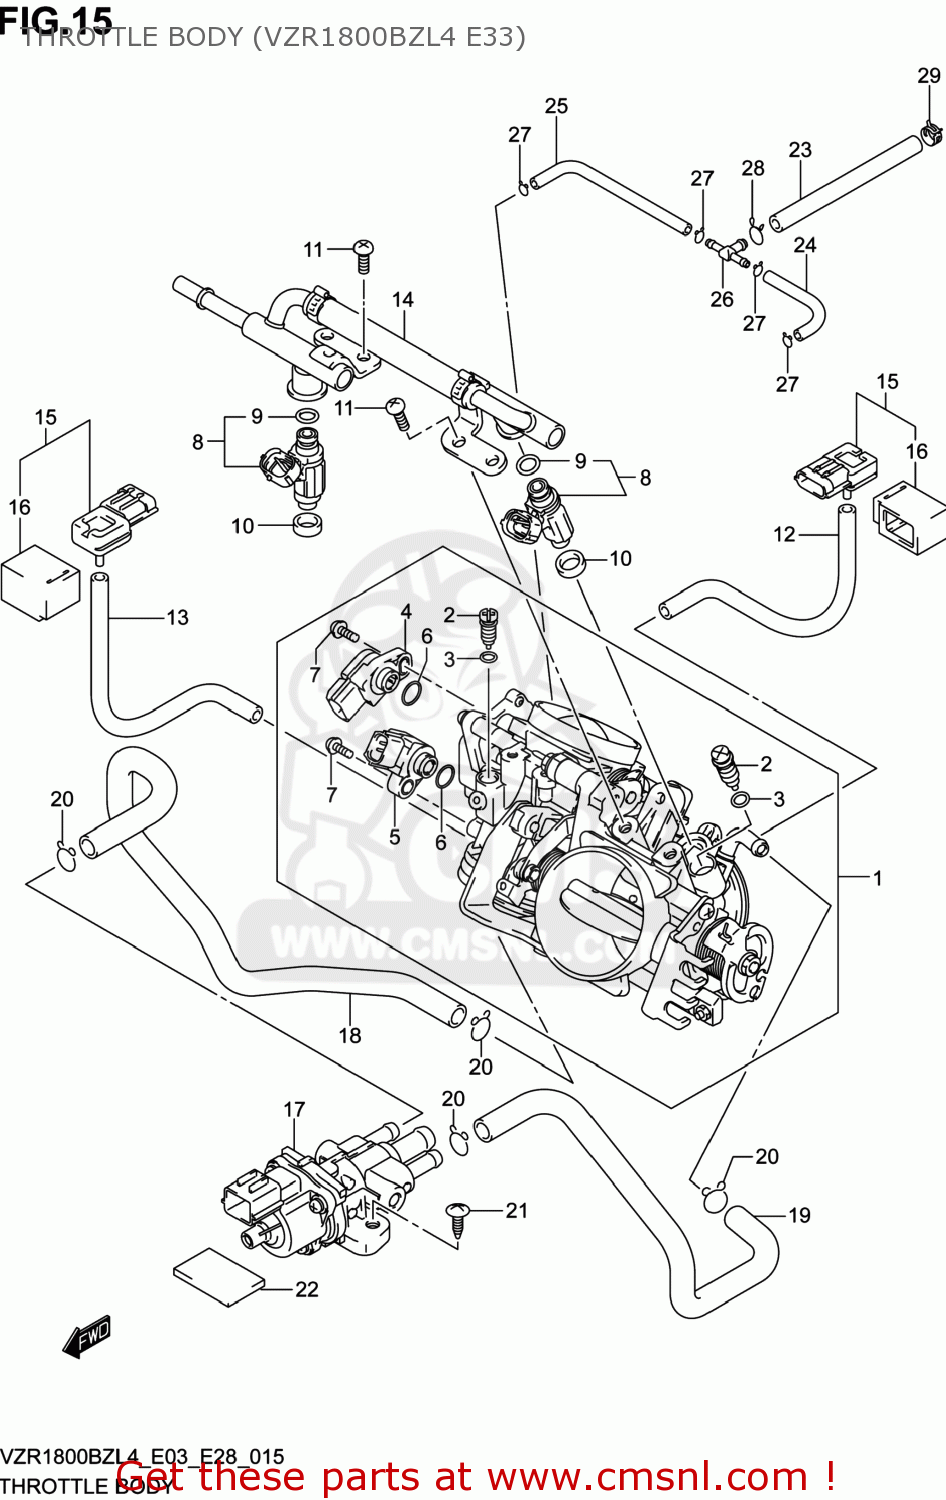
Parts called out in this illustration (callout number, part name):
1	BODY ASSY,THROTTLE
2	ADJUSTER
3	O RING
4	SENSOR ASSY
5	SENSOR ASSY
6	O RING
7	SCREW
8	INJECTOR ASSY
9	O-RING
10	SEAL
11	SCREW
12	HOSE
13	HOSE
14	PIPE ASSY,DELIVERY
15	SENSOR,AIR PRESSURE
16	COVER
17	VALVE,ISC
18	HOSE,ISC VALVE,R
19	HOSE,ISC VALVE,L
20	CLIP
21	SCREW
22	CUSHION,FUEL TANK NO.2
23	HOSE
24	HOSE
25	HOSE
26	NIPPLE
27	CLIP
28	CLIP
29	CLIP
